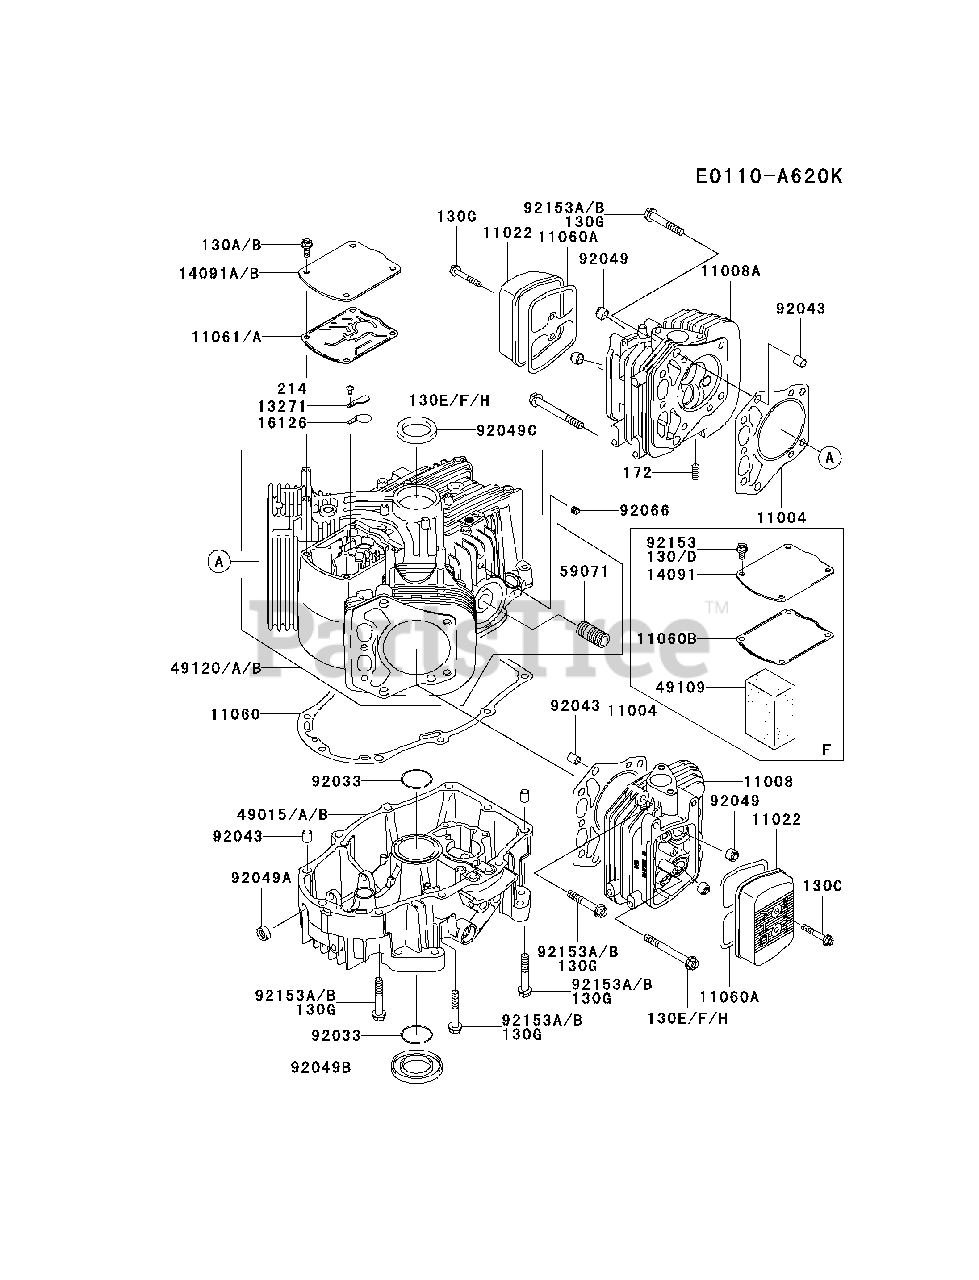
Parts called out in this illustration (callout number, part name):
130C	BOLT-FLANGED,6X40
130E	BOLT-FLANGED,8X75
172	BOLT-STUD,8X18
214	SCREW-PAN+-,4X8
